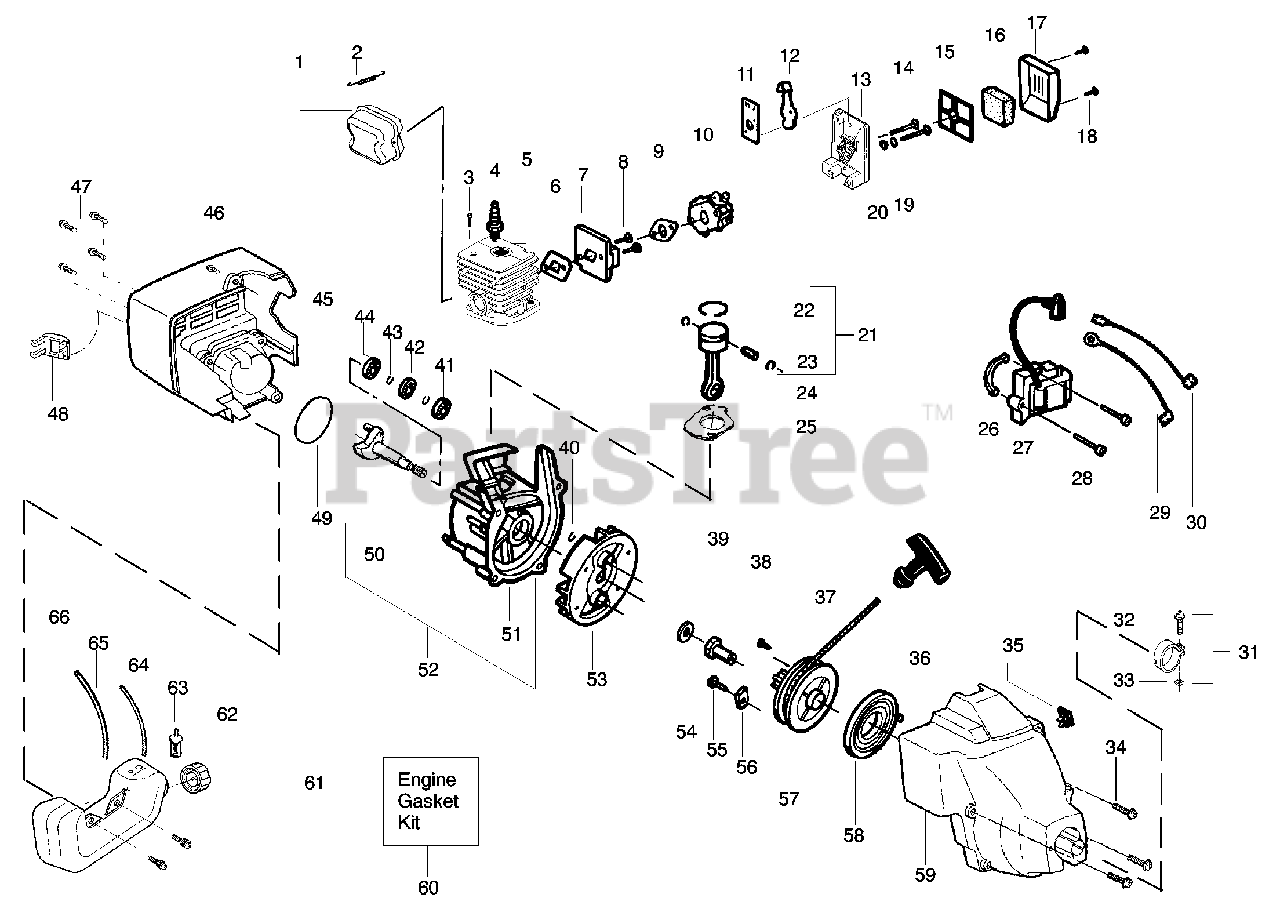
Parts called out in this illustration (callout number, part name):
1	Kit - Muffler
2	Spring-Muffler
3	Screw-Cylinder
4	Spark Plug (RCJ 6Y)
5	Kit - Cylinder
6	Gasket-Cyl/Carb.(kit)
7	Adaptor-Carb.
9	Gasket-Carb.(kit)
10	Kit - Carburetor Ass'y
11	Plate-Choke Mounting
12	Shutter-Choke
15	Plate - Filter Support
16	Foam-Air Filter
17	Cover-Air Filter
19	Spacer-Choke
21	Kit - Piston
22	Ring-Piston
23	Retainer-Piston Pin
24	Assy-Connecting Rod
25	Gasket-Cylinder (kit)
26	Spacer-Module
27	Module-Ignition
29	Assy-Ground Wire
30	Assy-Leadwire
31	Assy-Nose Cone Clamp
32	Screw-Nose Cone
33	Nut-Nose Cone
34	Screw
35	Kit-Momentary Switch
36	Handle-Starter
37	Kit - Rope
39	Coupling-Drive
40	Retain. Ring-C'shaft
41	Bearing-Outer
42	Seal-C'case
43	Retainer Ring-C'case
44	Bearing-Inner
45	Shroud-Rear
47	Screw
48	Guard-Muffler
49	O-Ring-C'case (kit)
50	Assy-Crankshaft
51	Assy-Crankcase
52	Assy-C'case & C'shaft
53	Assy-Flywheel
54	Washer-Flat
56	Retainer
57	Kit-Starter Pulley
58	Spring-Starter
59	KIT-Fan Hsg. Assy.
60	Kit-Engine Gasket
61	Retainer-Fuel Tank
62	Assy-Fuel Cap w/ret.
63	Assy-Fuel Pickup
64	Kit-Fuel Line (Small)
65	Kit-Fuel Line (Large)
66	Assy-Fuel Tank
